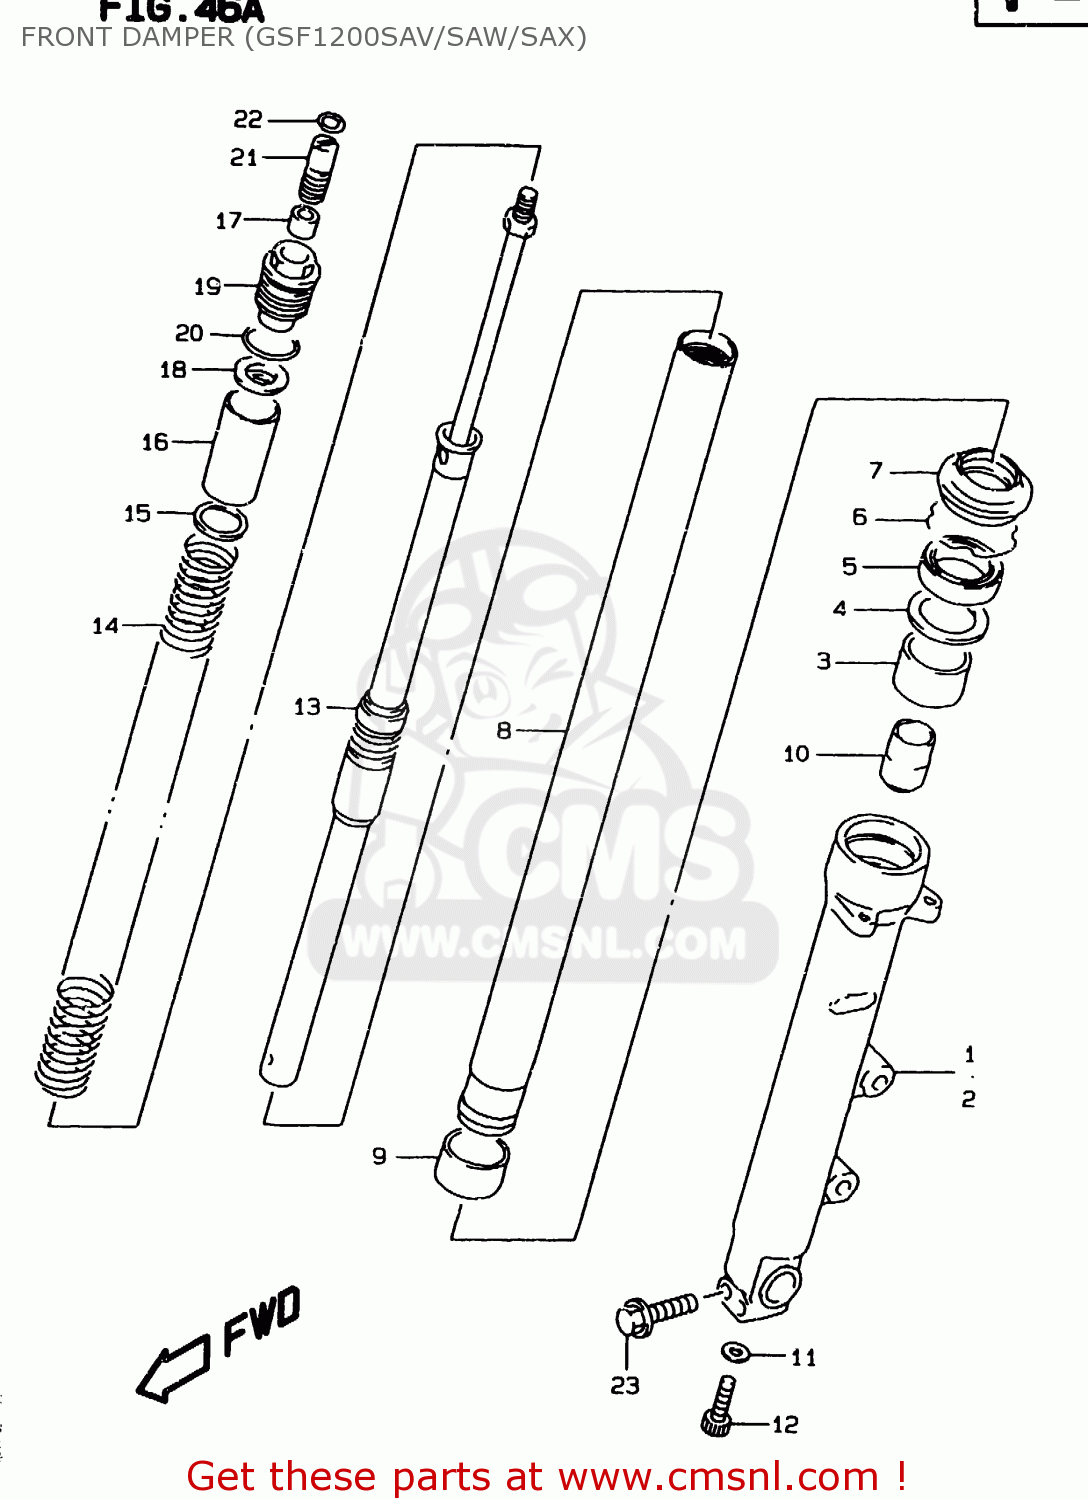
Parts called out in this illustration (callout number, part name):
1	TUBE,OUTER,R
2	TUBE,OUTER,L
3	BUSH,GUIDE
4	SPACER,SEAL
5	SEAL,OIL
6	CIRCLIP,FORK OIL SEAL
7	SEAL,DUST
8	TUBE,INNER
9	BUSH,SLIDE
10	PIECE,OIL LOCK
11	GASKET (NAS)
12	BOLT(8X27)
13	ROD,FR DAMPER
14	SPRING,FR
15	SEAT,SPRING LWR
16	COLLAR,SPRING(35X37X50)
17	NUT
18	SEAT,SPRING UPR
19	BOLT,FORK
20	O RING(D:2.5,ID:13.8)
21	ADJUSTER,SPRING
22	O RING(D:2.5,ID:13.8)
23	BOLT
